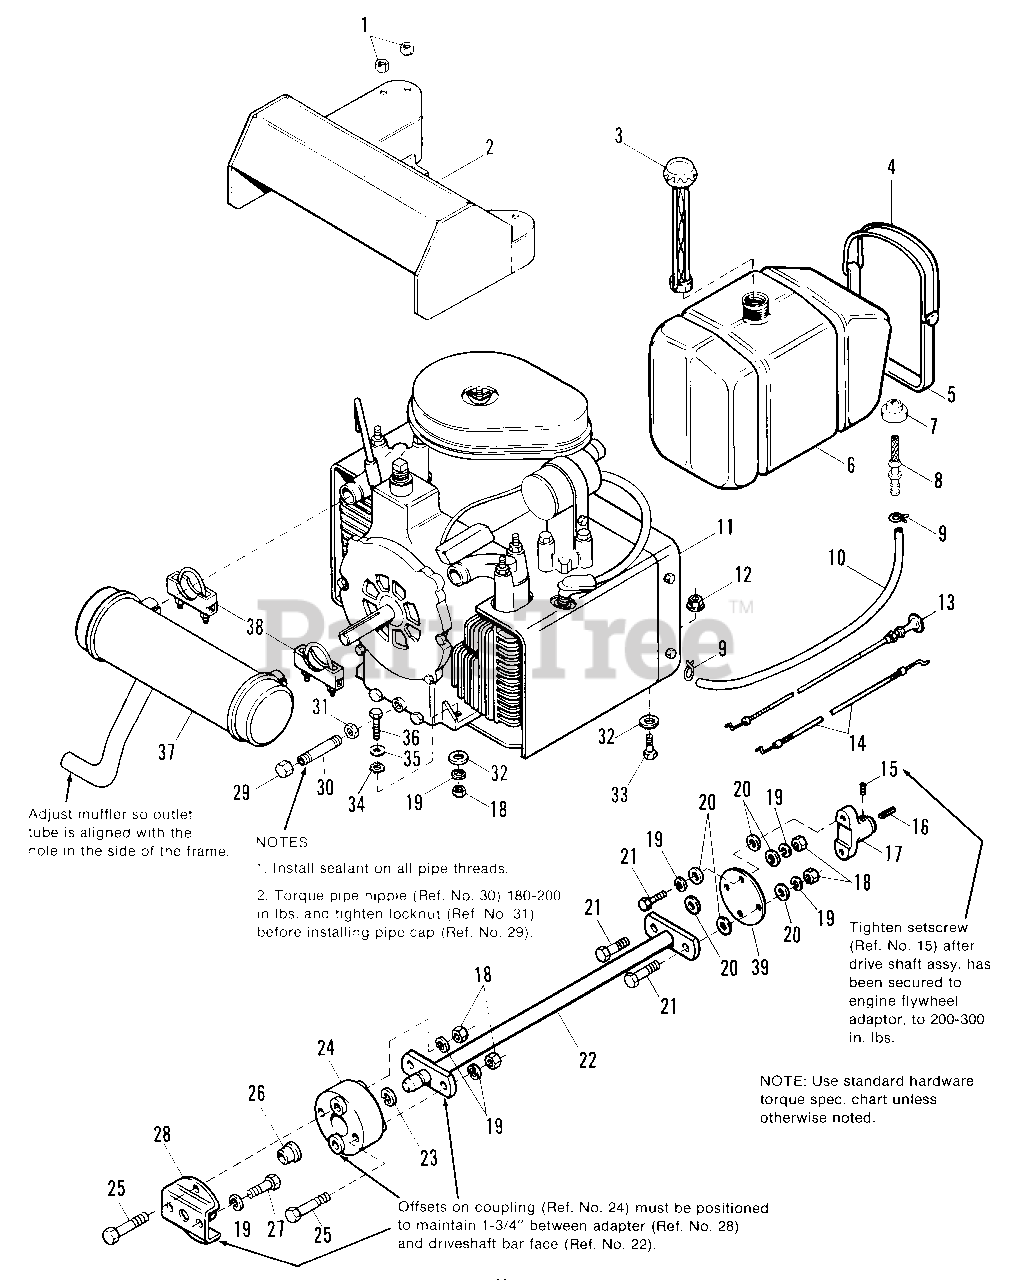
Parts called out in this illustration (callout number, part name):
1	LOCKNUT, 2 Way, 5/16-18
2	HEAT SHIELD ASSY.
3	CAP, Fuel Tank
4	STRAP, Fuel Tank
5	STRAP, Tank
6	TANK ASSY., Fuel
9	CLAMP, Hose
11	ENGINE, Kohler, 17 HP
12	NUT, Whizlock, 3/8-16 (Zinc Pltd.)
13	CHOKE CONTROL
14	THROTTLE CONTROL
15	SETSCREW, 3/8-24 x 3/8
16	KEY, Drive Shaft
17	FLANGE, Drive Shaft
18	NUT, Hex, 3/8-16
19	LOCKWASHER, 3/8
20	WASHER, Special
21	CAPSCREW, Hex Hd., 3/8-16 x 1-1/4
22	SHAFT ASSY., Drive
23	RETAINING RING
24	COUPLING, Compression
25	CAPSCREW, Hex Hd., 3/8-16 x 2-1/2
27	CAPSCREW, Hex Hd.
28	PLATE ASSY., Adaptor
29	CAP, Pipe, Hex
30	DRAIN, Oil
31	LOCKNUT, 3/8-18
32	WASHER, Plain, 3/8
33	CAPSCREW, Hex Hd., 3/8-16 x 1-1/4
34	LOCKWASHER, Ext. Tooth (Zinc Pltd.)
35	WASHER, 5/16 (Zinc Pltd.)
36	CAPSCREW, 3/8-16 x 1-1/2
37	MUFFLER, Exhaust
38	CLAMP, Exhaust
